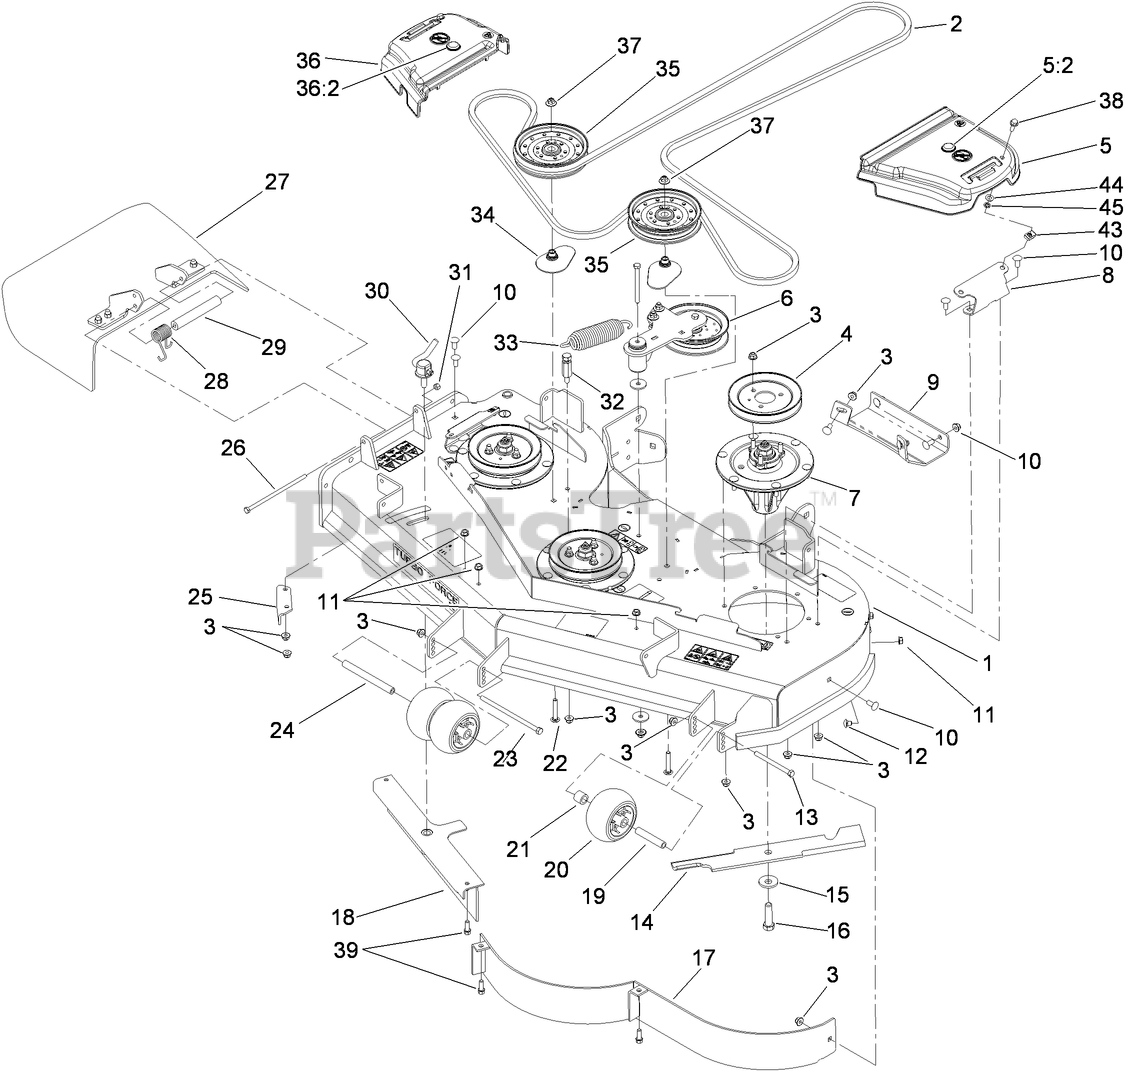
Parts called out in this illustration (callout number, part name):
1	DECK DECAL ASM
2	BELT-V
3	NUT-HF, NI
4	PULLEY
5	LH BELT COVER ASM
5:2	PLUG-PLASTIC
6	IDLER ARM ASM
7	SPINDLE ASM
8	BRACKET-COVER, BELT
9	PLATE-SKID
10	SCREW-CARR
11	NUT-HHF, WHIZ
12	SCREW-CARR
13	SCREW-HH
14	BLADE-18IN, HI FLOW
15	Washer-Blade Bolt, Heavy
16	SCREW-BLADE
17	BAFFLE ASM
18	BAFFLE
19	TUBE-SPANNER
20	ROLLER-SCALP, ANTI
21	TUBE-SPACER
22	BOLT-CARR, SHORT NECK
23	SCREW-HH
24	SPACER-WHEEL
25	BAFFLE-DISCHARGE
26	SCREW-HH
27	RUBBER DEFLECTOR ASM
28	SPRING-TORSION
29	SPACER
30	LEVER ASM
31	NUT-LOCK, NI
32	ANCHOR-SPRING, TALL
33	EXTENSION-SPRING
34	SPACER-PULLEY
35	PULLEY-IDLER, FLAT
36	RH BELT COVER ASM
36:2	PLUG-PLASTIC
37	NUT-FLANGE, NI
38	SCREW-HHF
39	SCREW-HWH
43	NUT-U
44	WASHER-THRUST
45	NUT-PUSH
